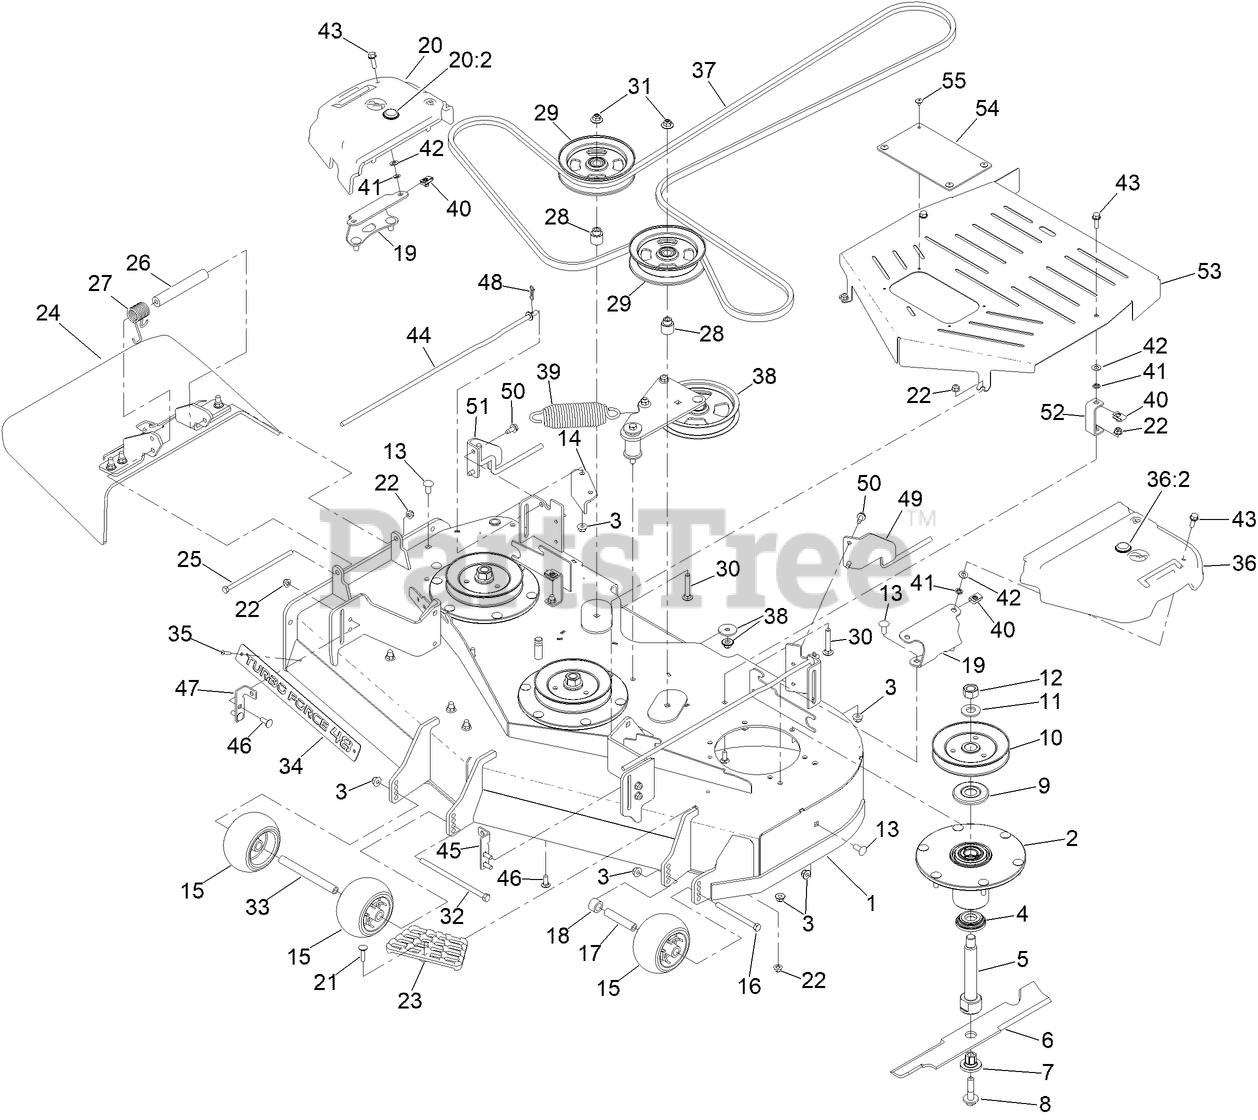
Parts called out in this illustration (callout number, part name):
1	DECK DECAL ASM
2	SPINDLE ASM
3	NUT-HF, NI
4	GUARD-BOTTOM
5	SHAFT-SPINDLE
6	BLADE-16.50 HIGH FLOW
7	BUSHING-HEX
8	SCREW-SEMS
9	GUARD-BEARING, TOP
10	SHEAVE,BLADE DRIVE 5.91
11	WASHER
12	NUT-HEX
13	SCREW-CARR
14	BAFFLE-DISCHARGE
15	ROLLER-SCALP, ANTI
16	SCREW-HH
17	TUBE-SHAFTING
18	TUBE-SPACER
19	BRACKET-COVER, BELT
20	RH BELT COVER ASM
20:2	PLUG-PLASTIC
21	SCREW-CARR
22	NUT-HF, NI
23	STEP-DECK
24	RUBBER DEFLECTOR ASM
25	SCREW-HH
26	SPACER
27	SPRING-TORSION
28	BUSHING, IDLER
29	PULLEY-IDLER, FLAT
30	SCREW-CARR
31	NUT-FLANGE, NI
32	SCREW-HH
33	SPACER-WHEEL
34	PLATE-TURBO FORCE [BLACK]
35	RIVET-TRIFOLD
36	LH BELT COVER ASM
36:2	PLUG-PLASTIC
37	BELT-V
38	IDLER ARM ASM
39	SPRING-EXTENSION
40	NUT-U
41	NUT-PUSH
42	WASHER-THRUST
43	SCREW-HHF
44	ROD-SKIRT, LOWER
45	BRACKET-SUPPORT, LH
46	BOLT-CARR
47	BRACKET-SUPPORT, RH
48	PIN-COTTER, LOCKING
49	SUPPORT-LOWER LH
50	SCREW-HWHTF
51	SUPPORT-LOWER RH
52	BRACKET-GUARD
53	GUARD-CENTER BELT 48
54	SHIELD-RUBBER
55	RIVET-POP
